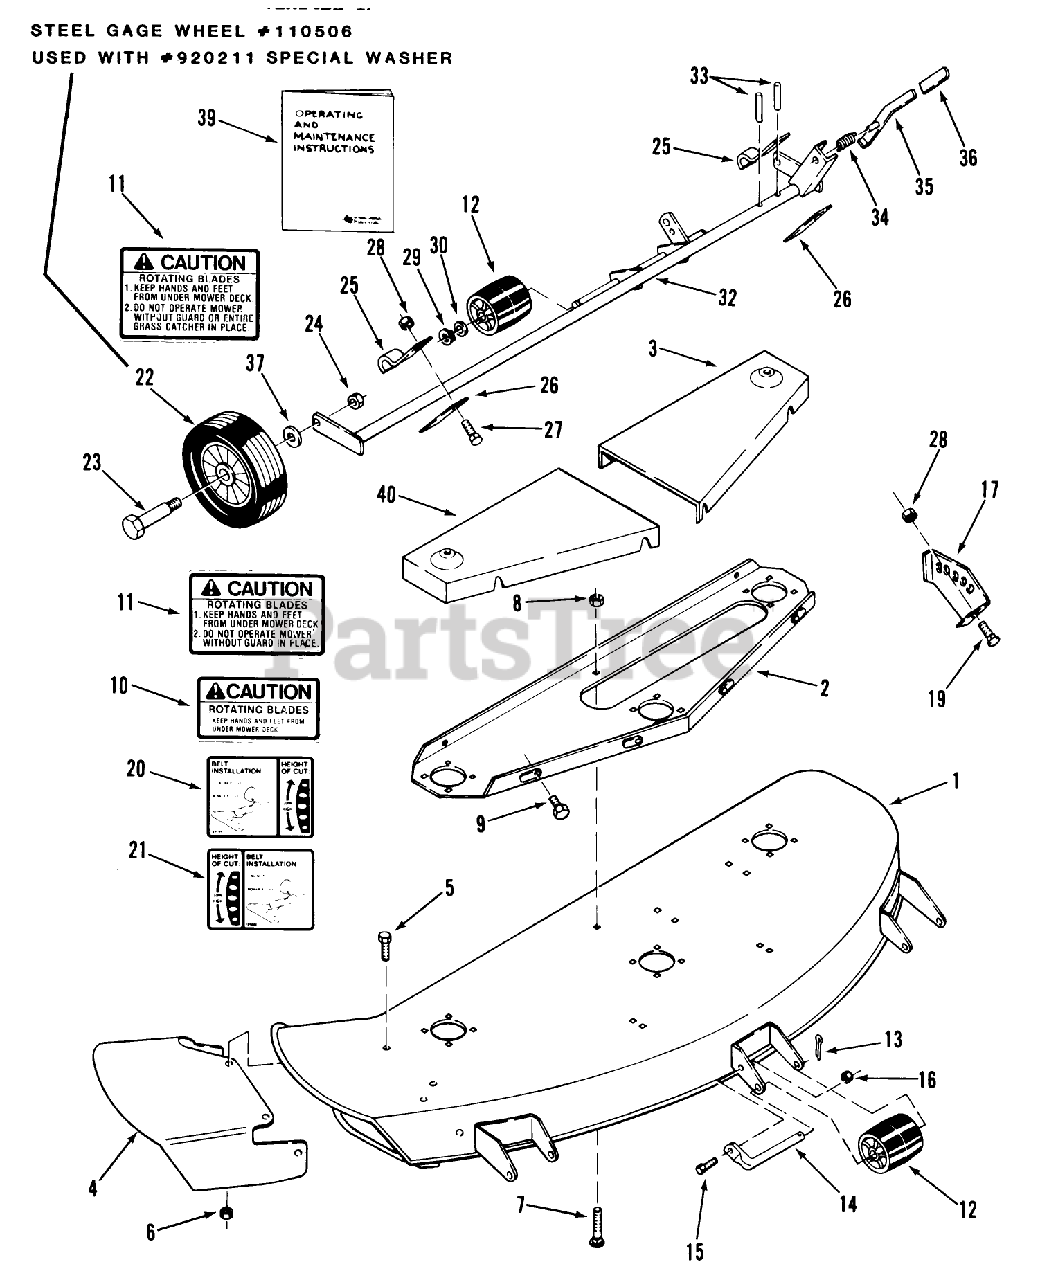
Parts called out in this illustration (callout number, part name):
20	DECAL-HEIGHT & BELT
21	DECAL-HEIGHT & BELT
23	BOLT-SHOULDER
33	PIN-SPIROL
34	SPRING-COMPRESSION
37	WASHER-FLAT
39	Operating and Maintenance Instructions
